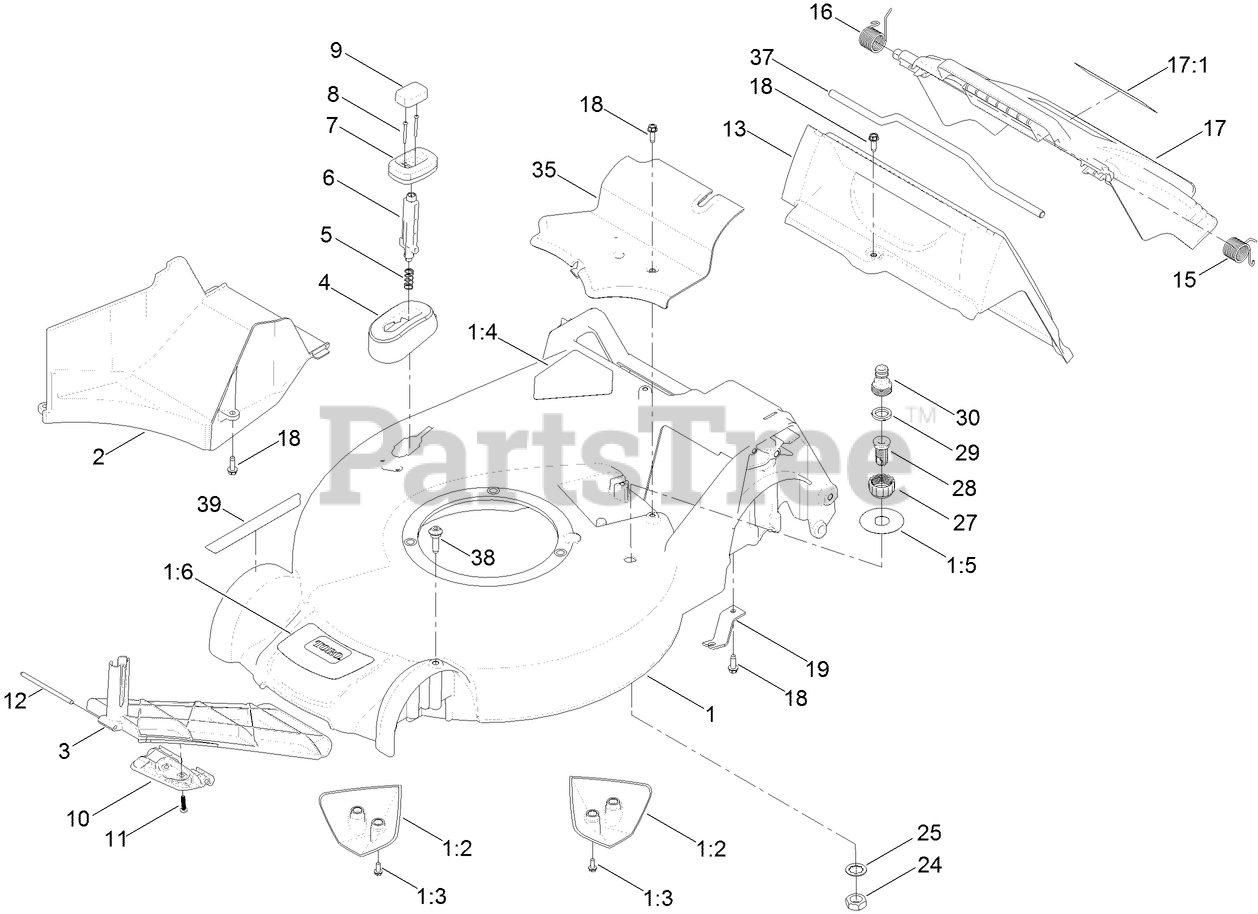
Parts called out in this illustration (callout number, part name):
1	HOUSING ASM
1:2	KICKER-FRONT
1:3	SCREW-TAPTITE
1:4	DECAL-DANGER
1:5	DECAL-PORT, WASHOUT
1:6	DECAL-DECK, SUPER RECYCLER
2	RAMP-DISCHARGE
3	DOOR-RECYCLE
4	COVER-DOOR, RECYCLE
5	SPRING-COMPRESSION
6	LATCH-RECYCLE
7	HOUSING-KNOB
8	SCREW-TORX, PAN HEAD
9	KNOB-RECYCLE
10	HINGE-DOOR, RECYCLE
11	SCREW-PLASTITE
12	PIN-HINGE
15	SPRING-TORSION
16	SPRING-TORSION
17	REAR DOOR ASM
17:1	DECAL-WARNING
18	SCREW-HWHTF
19	BRACKET-CABLE, TRACTION
24	NUT-JAM
25	WASHER-LOCK
27	COUPLING-HOSE, WASHOUT PORT
28	PORT-WASHOUT
29	WASHER-SEAL, WASHOUT PORT
30	ADAPTER-CONNECT, QUICK
35	COVER-BELT
37	ROD-DEFLECTOR
38	SCREW-SHOULDER, BHTF
39	DECAL-HOC
